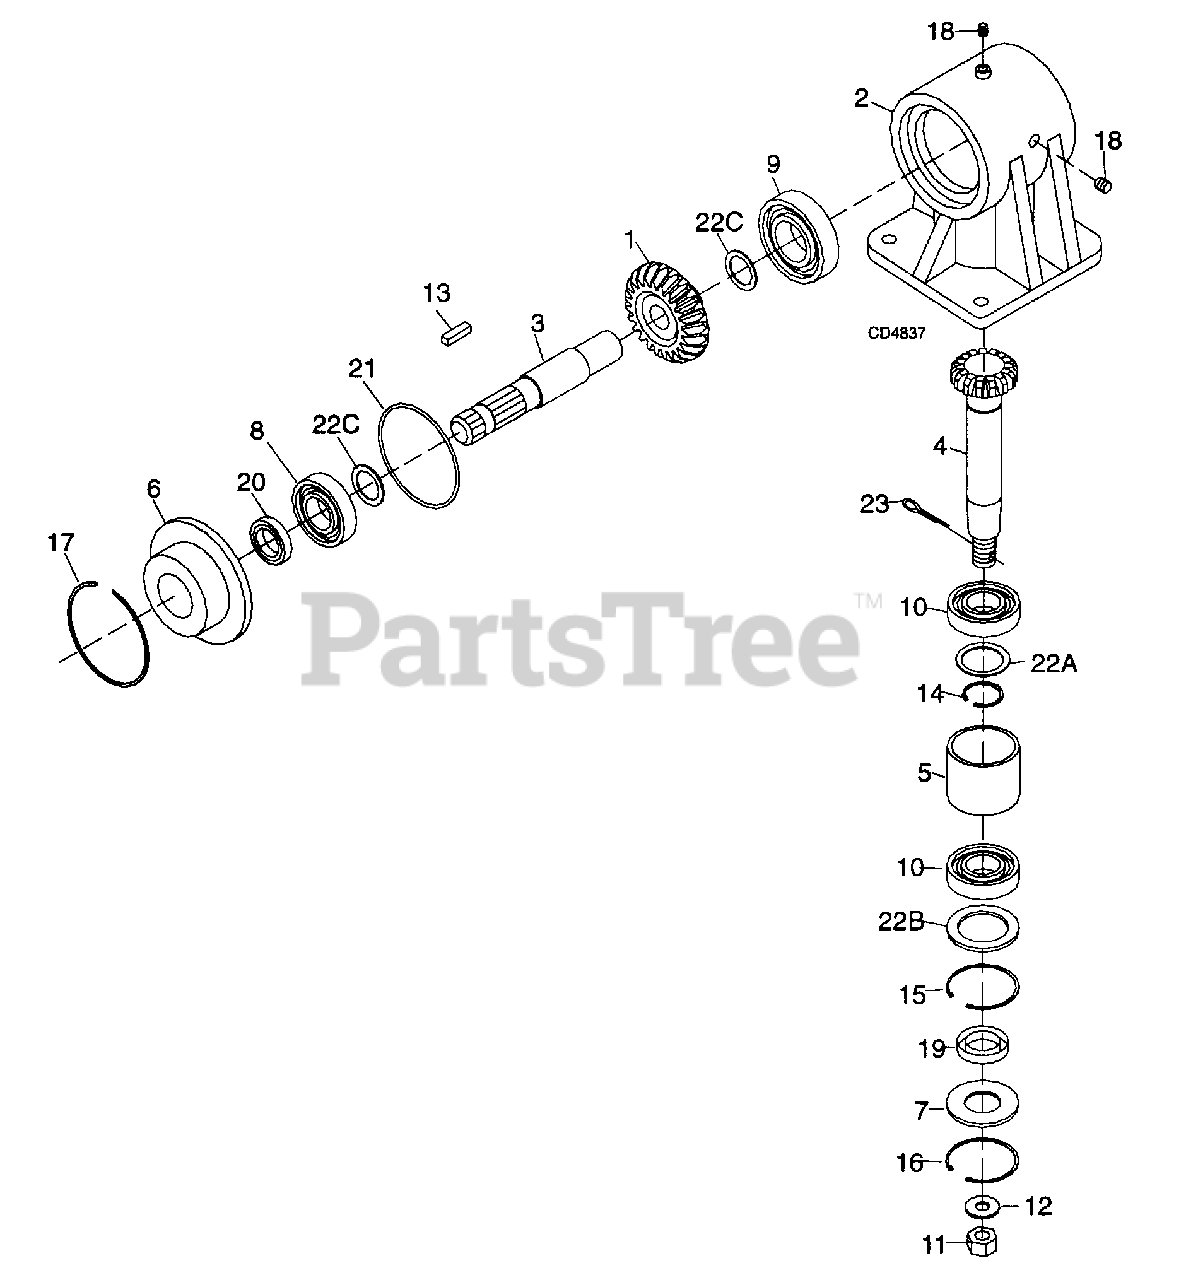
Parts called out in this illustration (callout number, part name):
1	Gear, bevel 1.38 x 4.5 x 23T
2	Housing, gearbox
3	Shaft, gear keyed 8.75
4	Shaft, pinion 12T
5	Spacer, 2.76 x 3.00 x 3.3
6	Cover, gearbox
7	Washer, 1.58 x 3.13 x .04
8	Bearing, ball 6007
9	Bearing, ball 6207
10	Bearing, ball 6208
11	Nut, castle M24 x 2
12	Washer, 25mm x 44mm x 4mm
13	Key, 8mm x 10mm x 30mm
14	Ring, internal retaining 45mm
15	Ring, internal retaining 2.9mm x 80mm
16	Ring, internal retaining 81mm
17	Ring, internal retaining 125mm
18	3/8NPT Square head pipe plug
19	Seal, metric 40 x 80 x 12
20	Seal, metric 35 x 52 x 7
21	Seal, o-ring .13 x 4.88 OD
22	Seal kit
